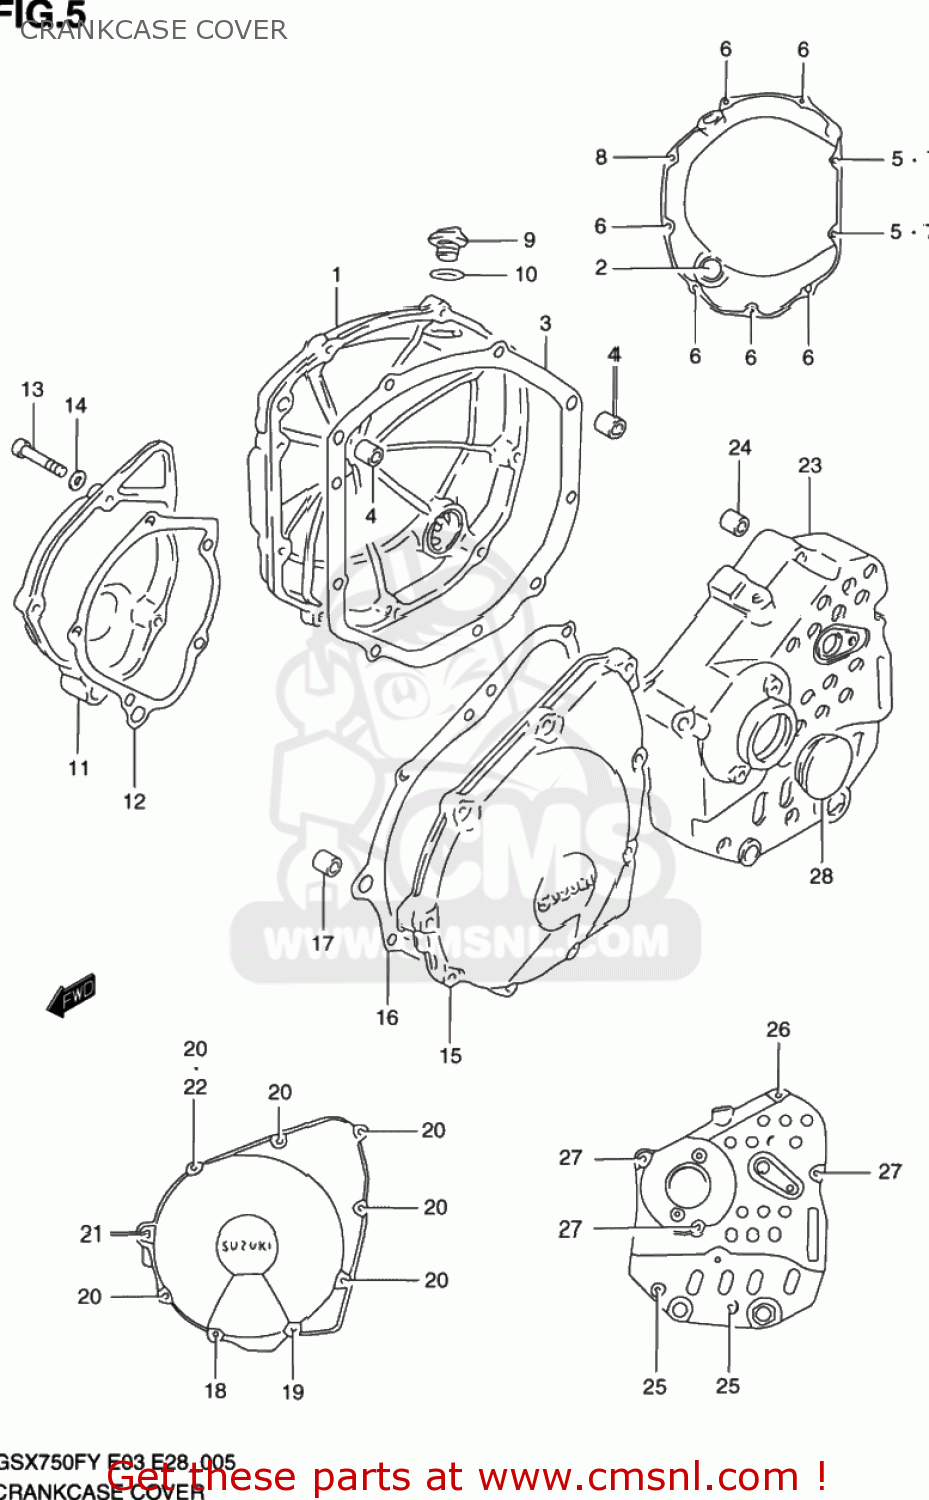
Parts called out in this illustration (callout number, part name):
1	COVER,CLUTCH
2	LENS,OIL LEVEL CHECK
3	GASKET,CL COVER (NAS)
4	PIN
5	GASKET(5.8X11X1.2) (NAS)
6	BOLT,CL.COVER
7	BOLT
8	BOLT
9	PLUG
10	O RING(D:3.1,ID:16.8)
11	COVER,SIGNAL GENERATOR
12	GASKET,SIGNAL GEN COVER (NAS)
13	BOLT(6X22)
14	GASKET(5.8X11X1.2) (NAS)
15	COVER,STARTER GEAR
16	GASKET,STARTER GEAR COVER (NAS)
17	PIN(8.4X11X20)
18	BOLT,OIL FILLE
19	BOLT,CRKCASE,R
20	BOLT,CL.COVER
21	BOLT
22	GASKET(5.8X11X1.2) (NAS)
23	COVER,ENGINE SPROCKET
24	PIN
25	BOLT
26	BOLT
27	BOLT
28	CAP(OD:36)
